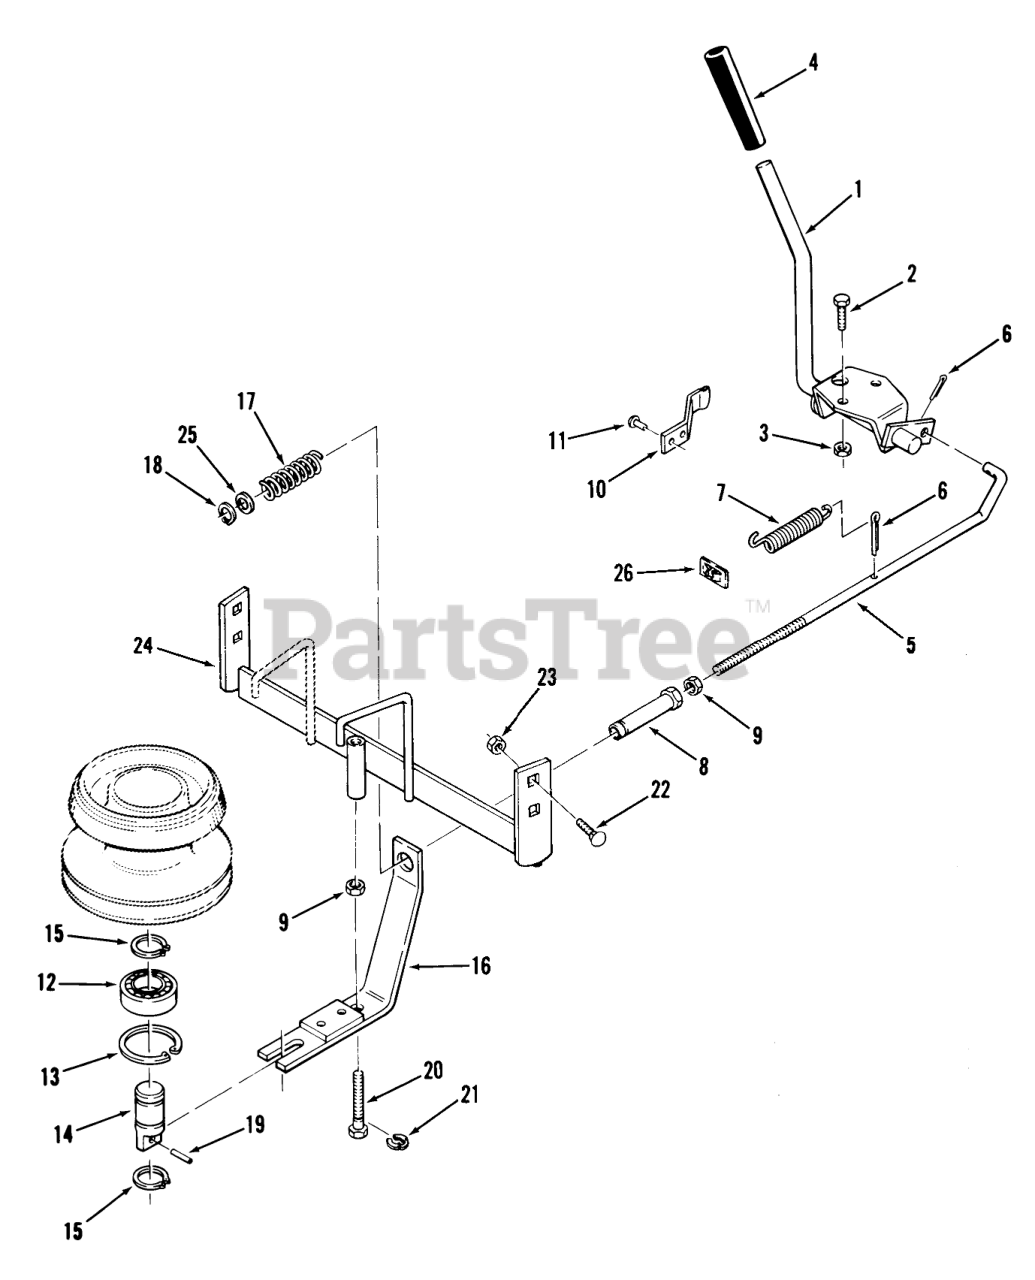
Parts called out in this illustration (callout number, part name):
1	PTO Clutch Lever
2	Bolt
3	Nut
4	GRIP
5	PTO Clutch Rod
6	Cotter Pin
7	Spring
8	TUBE-CLUTCH SPACER
9	Jam Nut 5/16-18
10	SPRING
11	RIVET
12	BaIl Bearing
13	Ring-Snap
14	Shaft Clutch Hsg
15	RING-SNAP, EXTERNAL
16	Clutch Brake Bracket
17	SPRING-CLUTCH
18	Retaining Ring
19	SPIROL PIN 7/32X7/8
20	SCREW-CLUTCH ADJUST
21	E-Ring
22	Bolt
23	Nut
24	Clutch Mounting Bracket
24	Clutch Mounting Bracket 216-5 Only
25	Washer
26	SPEED NUT
